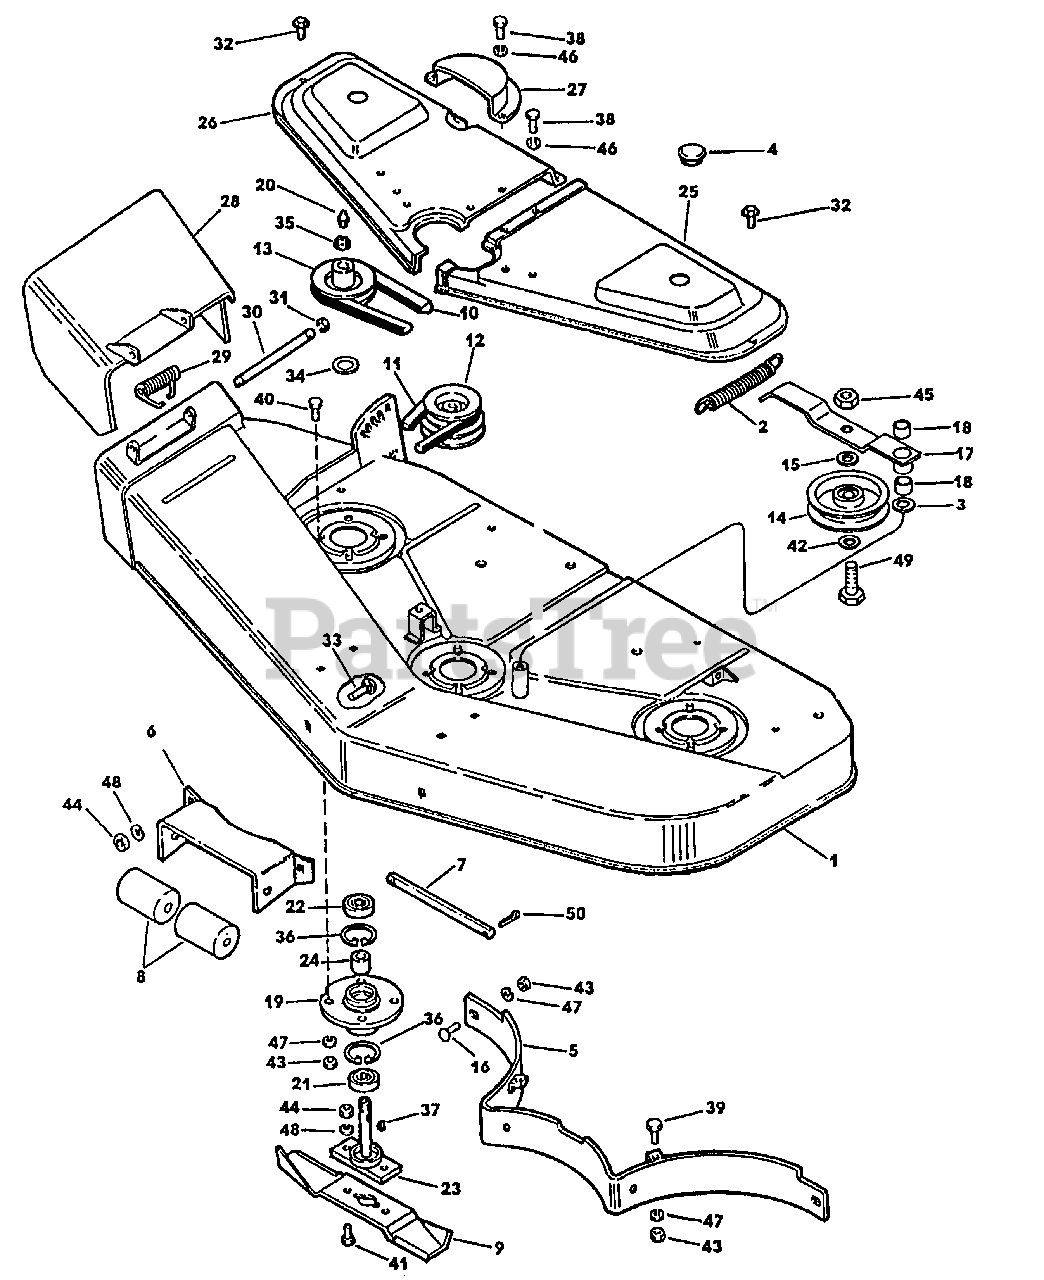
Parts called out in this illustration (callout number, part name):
1	Cutter Housing & Decal Ass'y. (42" Only)
2	Spring
3	Washer
4	Plug
5	Baffle (42" Only)
6	Bracket, Roller
7	Shaft, Roller
8	Roller
9	Blade (42" Only)
10	V-Belt, Deck (48" Only)
11	V-Belt, Drive
12	Pulley, Drive (42" Only)
13	Pulley, Blade Spindle
14	Pulley, Idler
15	Spacer
16	Carriage Bolt
17	Idler Arm & Bearing Assy.
18	Bearing, Sleeve
19	Spindle Housing
20	Grease Fitting
21	Bearing, Lower
22	Bearing, Upper
23	Spindle
24	Sleeve
25	Cover Ass'y-L.H. (42" Only)
26	Cover Ass'y-R.H. (42" Only)
27	Guard, Drive Belt
28	Chute Extension
29	Spring, Chute Extension
30	Shaft, Chute Extension
31	E-Ring
32	Thread Forming Screw, Hex Hd
33	Bolt, Carriage
34	Spacer
35	Locknut, Special
36	Retaining Ring
37	Key, Woodruff
38	Cap Screw, Hex Hd.
39	Cap Screw, Hex Hd
40	Cap Screw, Hex Hd
41	Cap Screw, Hex Hd
42	Washer, Thrust
43	Nut, Hex
44	Nut, Hex
45	Nut, Hex
46	Washer, Spring Lock
47	Washer, Spring Lock
48	Washer, Spring Lock
49	Bolt, Special
50	Pin, Cotter
